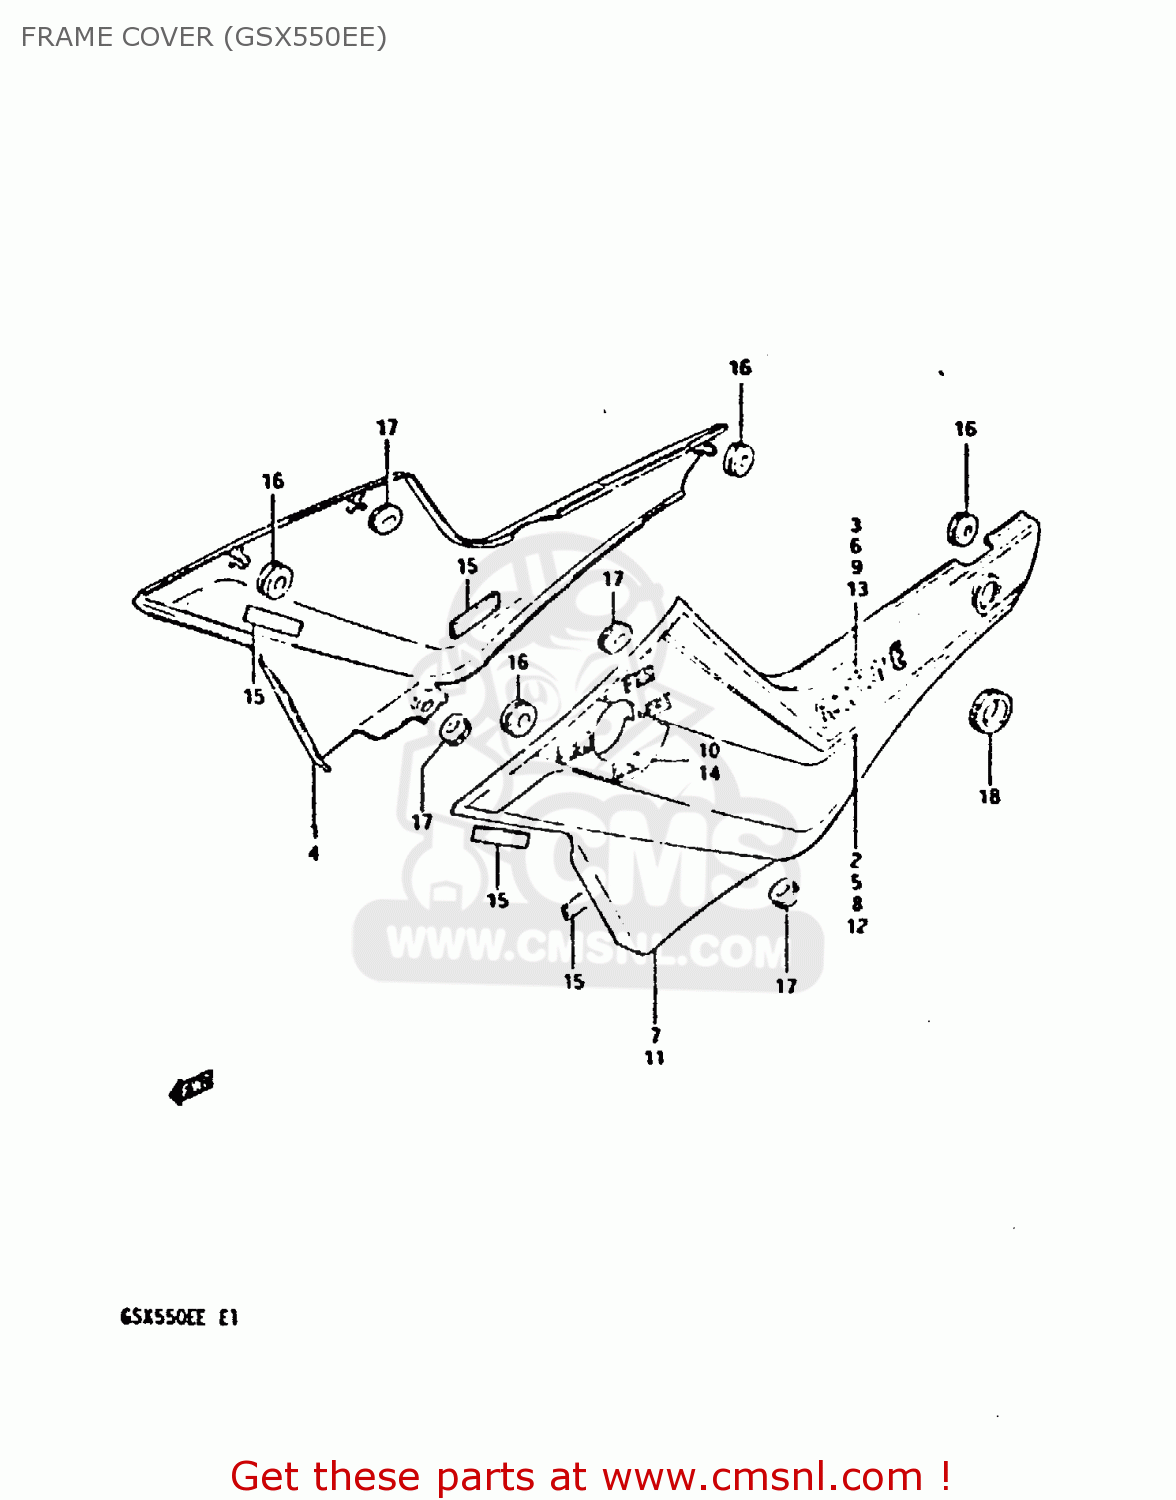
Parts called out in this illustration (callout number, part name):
1	COVER, FRAME RH (BLACK)
2	TAPE SET, FRAME COVER RH
3	EMBLEM
4	COVER, FRAME RH (RED)
5	TAPE SET, FRAME COVER RH
6	EMBLEM
7	COVER, FRAME LH (BLACK)
8	TAPE SET, FRAME COVER LH
9	EMBLEM
10	EMBLEM, FUEL COCK
11	COVER, FRAME LH (RED)
12	TAPE SET, FRAME COVER LH
13	EMBLEM
14	EMBLEM, FUEL COCK
15	RUBBER,FRAME COVER
16	CUSHION
17	CUSHION
18	GROMMET,SEAT LOCK HOLE
